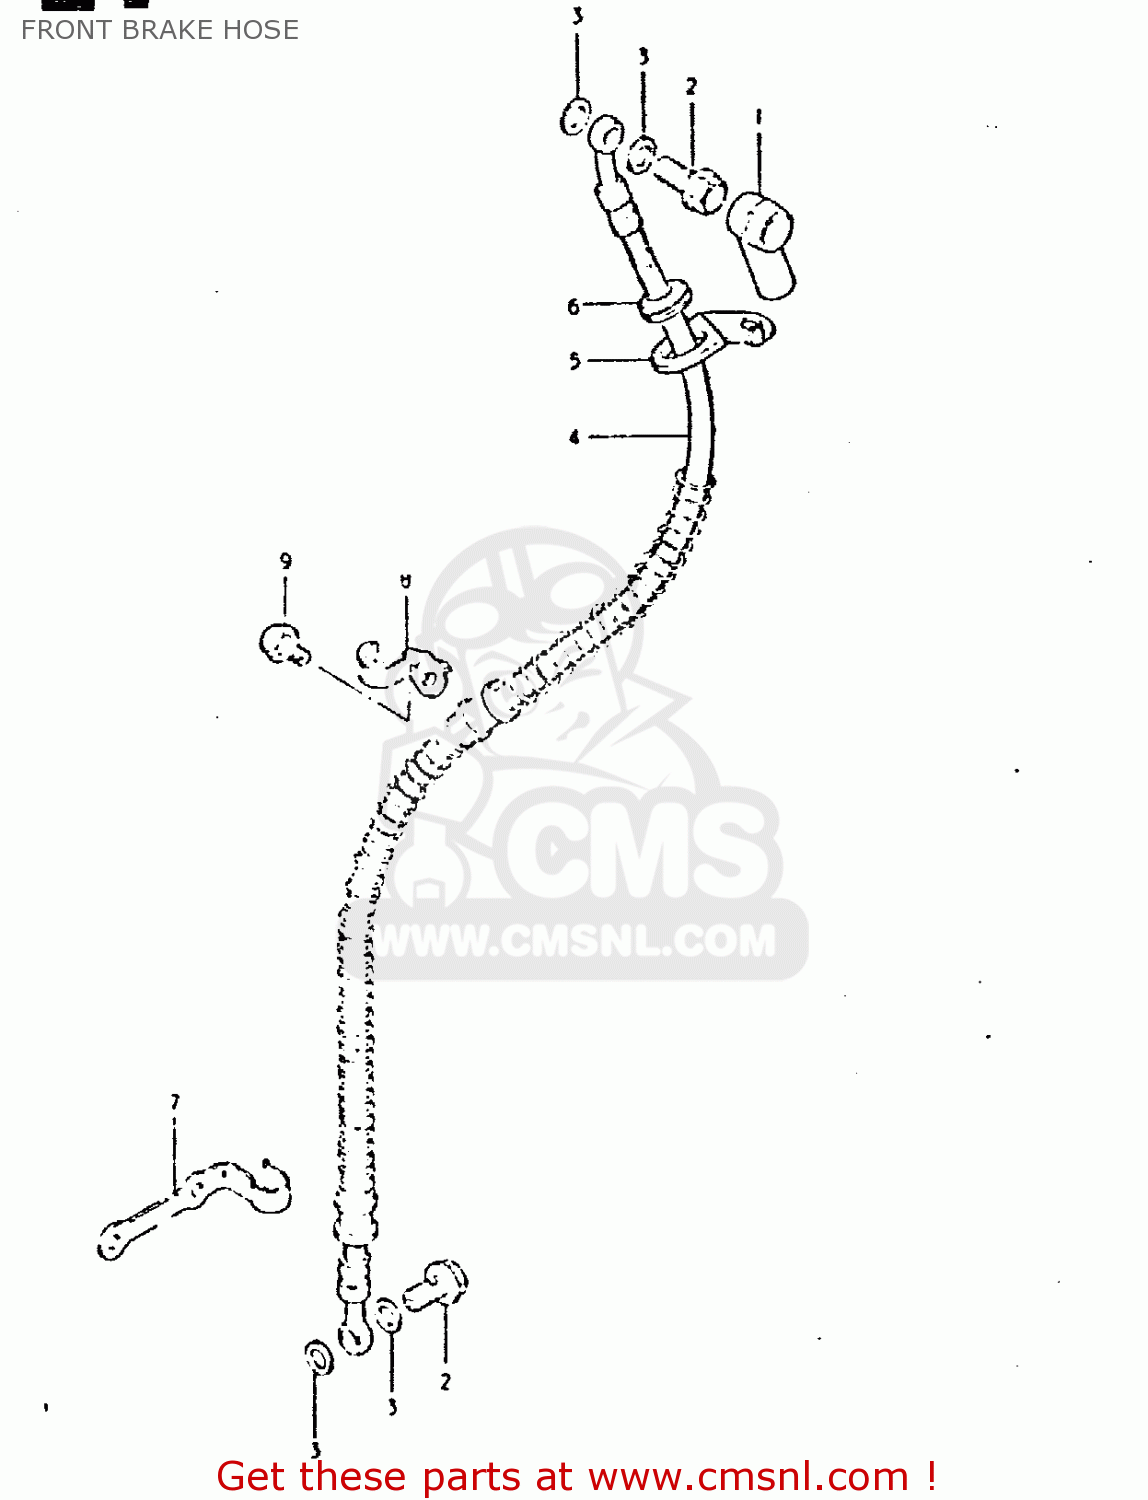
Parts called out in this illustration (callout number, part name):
1	BOOT,MASTER CYLINDER
2	BOLT,UNION
3	WASHER
4	HOSE,FRONT BRAKE
5	GUIDE,BRAKE HOSE
6	GROMMET
7	GUIDE,BRAKE HOSE NO.2
8	GUIDE,BRAKE HOSE NO.3
9	BOLT
